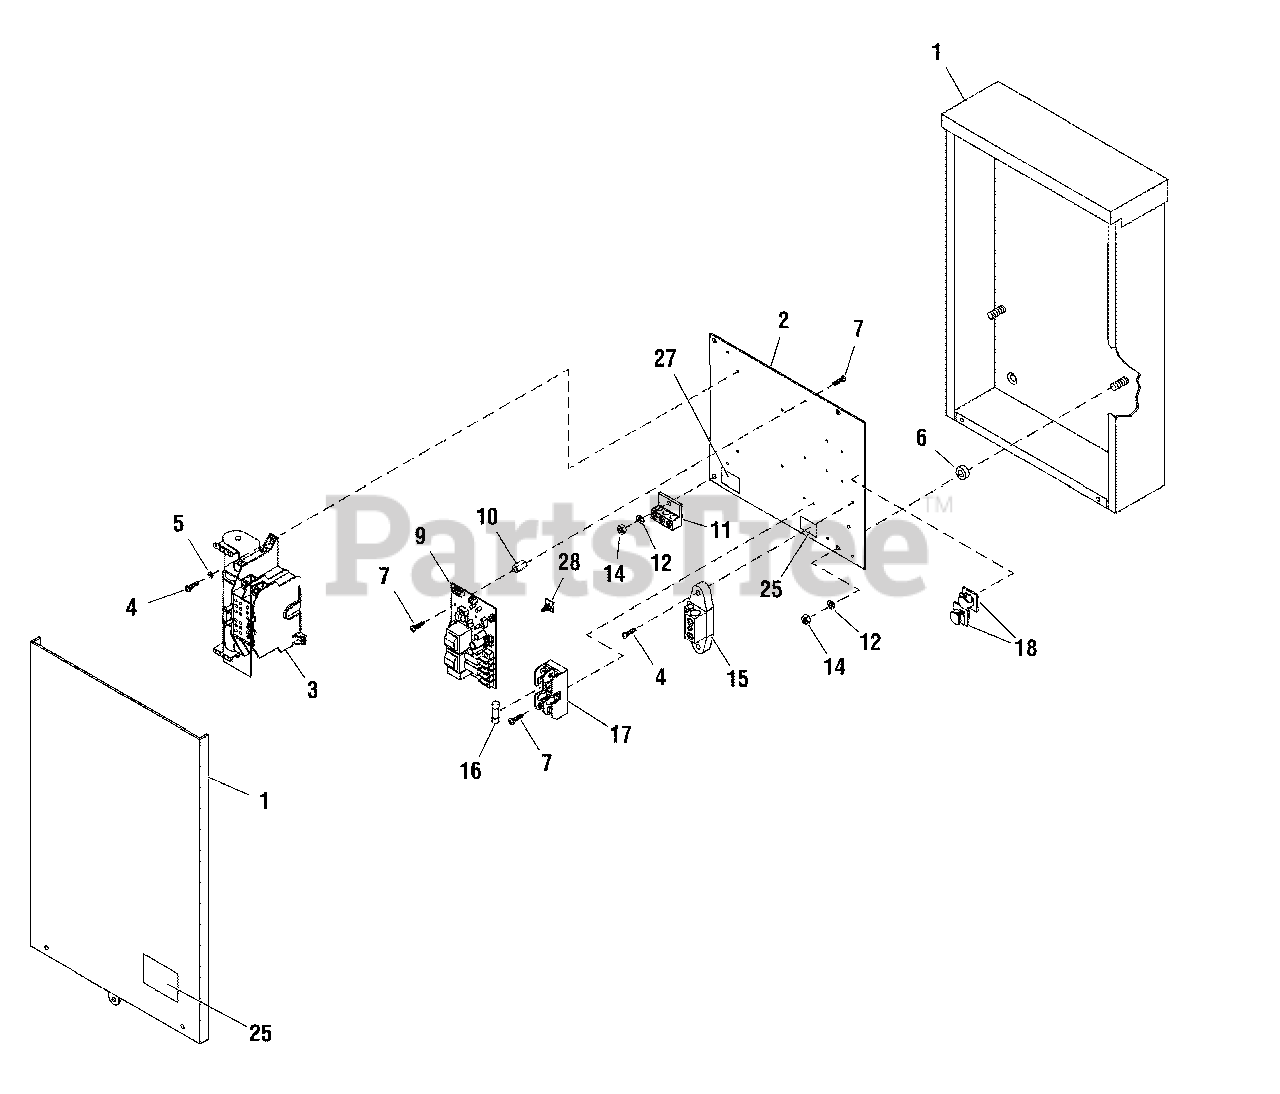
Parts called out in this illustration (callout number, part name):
1	ENCLOSURE
2	PANEL, Back
3	SWITCH, Transfer
4	* SCREW, Phillips Head, #10 - 32 x 1/2
5	* WASHER, Ext. Tooth, #10
6	SPACER
7	* SCREW, Phillips Head, #6-32 x 3/8
9	BOARD, Circuit
10	SPACER
11	GROUND LUG
12	* WASHER, Lock 1/4
14	* NUT, 1/4-20
27	DECAL
